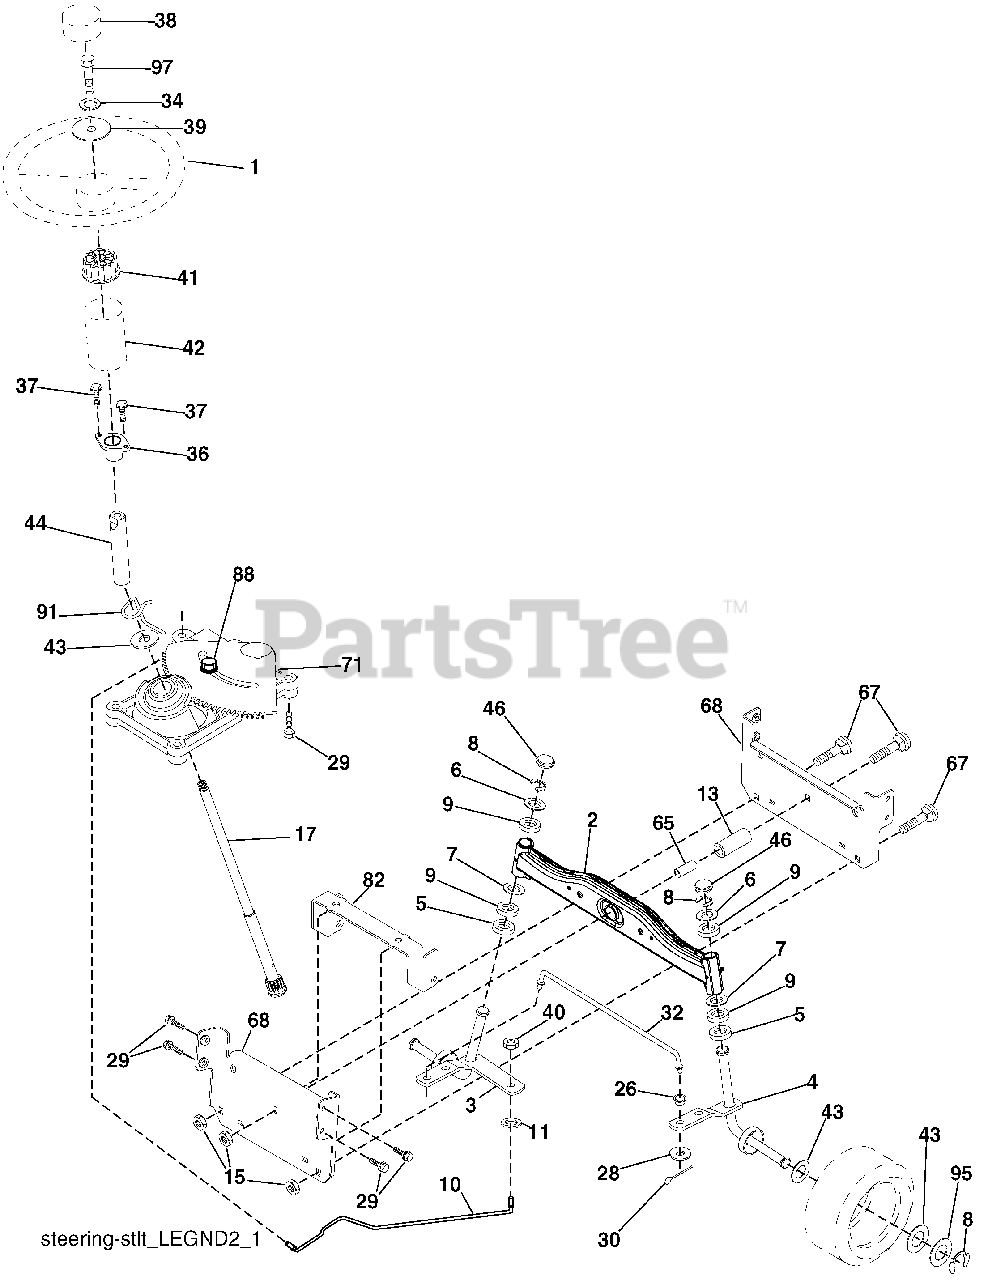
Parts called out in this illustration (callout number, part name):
1	Wheel Steering
2	Axle Asm
3	Spindle Asm LH
4	Spindle Asm RH
5	Bearing Race Thrust Harden
6	Washer 25/32 x 1-5/8 x 16 Ga.
7	Washer 27/32 x 1-1/4 x 16 Ga.
8	Ring Clip #t5304-75
9	Bearing Col STRG.
10	Link Drag
11	Washer Lock Hvy Hlcl Spr 3/8
13	Spacer Axle Front
15	Hexflange Lock
17	Shaft Asm Strg
26	Bushing Link Drag Blk LR
28	Washer 13/32 x 7/8 x 16 Ga.
29	Screw 3/8-16 x 3/4
30	Pin Cotter 1/8 x 3/4 Cad
32	Rod Tie Wire Form 19 75 Mech
34	Washer Lock 5/16
36	Bushing Strg 5/8 Id Dash
37	Screw
38	Cap Wheel Steer
39	Washer 11/32 x 2 x 12 Ga.
40	Nut Crownlock 3/8-24
41	Adapter Wheel Strg
42	Boot Dash Mtl Steering Blk
43	Washer 25/32 x 1 1/4 x 16 Ga.
44	Extension Steering
46	Cap Spindle Fr Top Blk
65	Spacer Brace Axle
67	Bolt RDHD SQNK 3/8-16 x 2-1/4
68	Brace Axle
71	Steering Asm.
82	Bracket Susp Chassis Front
88	Bolt Shoulder 7/16-20
91	Clip Steering
95	Washer Harden .793 x 1.637 x 060
97	Bolt 5/16-18 x 4 Gr. 5
